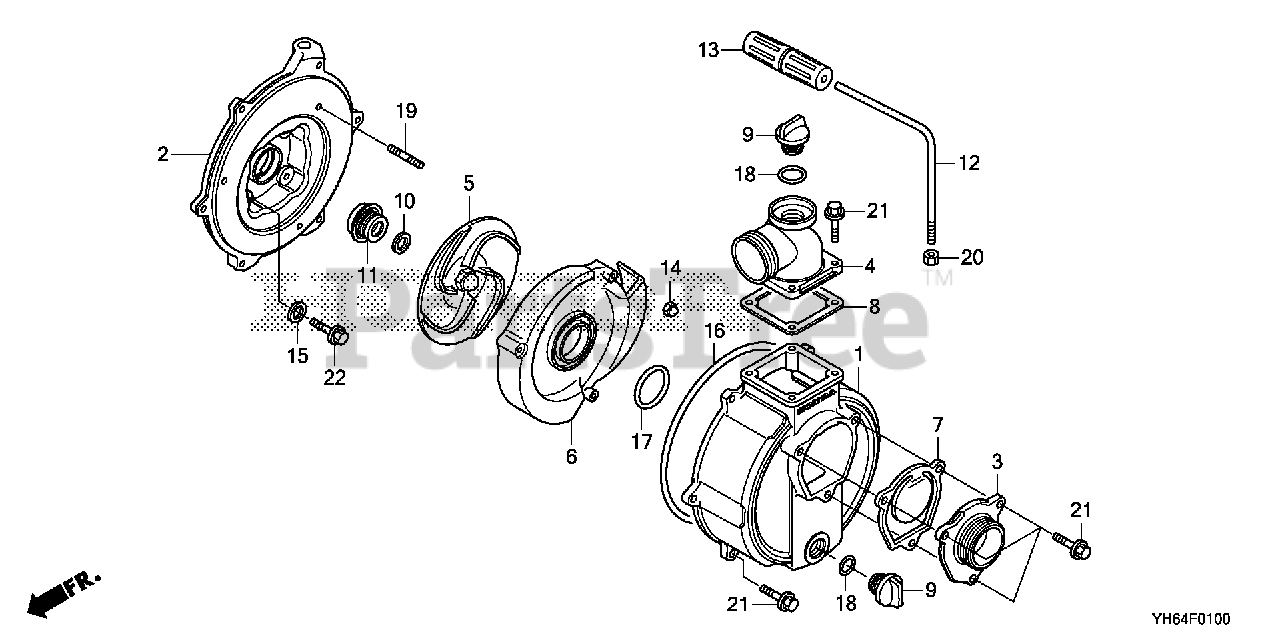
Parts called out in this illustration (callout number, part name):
2	COVER, CASING
3	INLET (NPTF1 1/2)
4	OUTLET (NPTF1 1/2)
5	IMPELLER
6	CASE, VOLUTE
7	VALVE, IN.
8	GASKET, OUTLET
9	CAP, FILLER
10	SHIM, ADJUSTER
11	SEAL ASSY., MECHANICAL
13	GRIP, HANDLE
14	NUT, CAP (6MM)
15	WASHER, SEALING (8MM)
16	O-RING (217.5X3.5)
17	O-RING (49X5.7)
18	O-RING (23.7X3.5)
19	BOLT, STUD (6X35)
20	NUT, HEX. (14MM)
21	BOLT, FLANGE (8X25)
22	BOLT, FLANGE (8X28)
